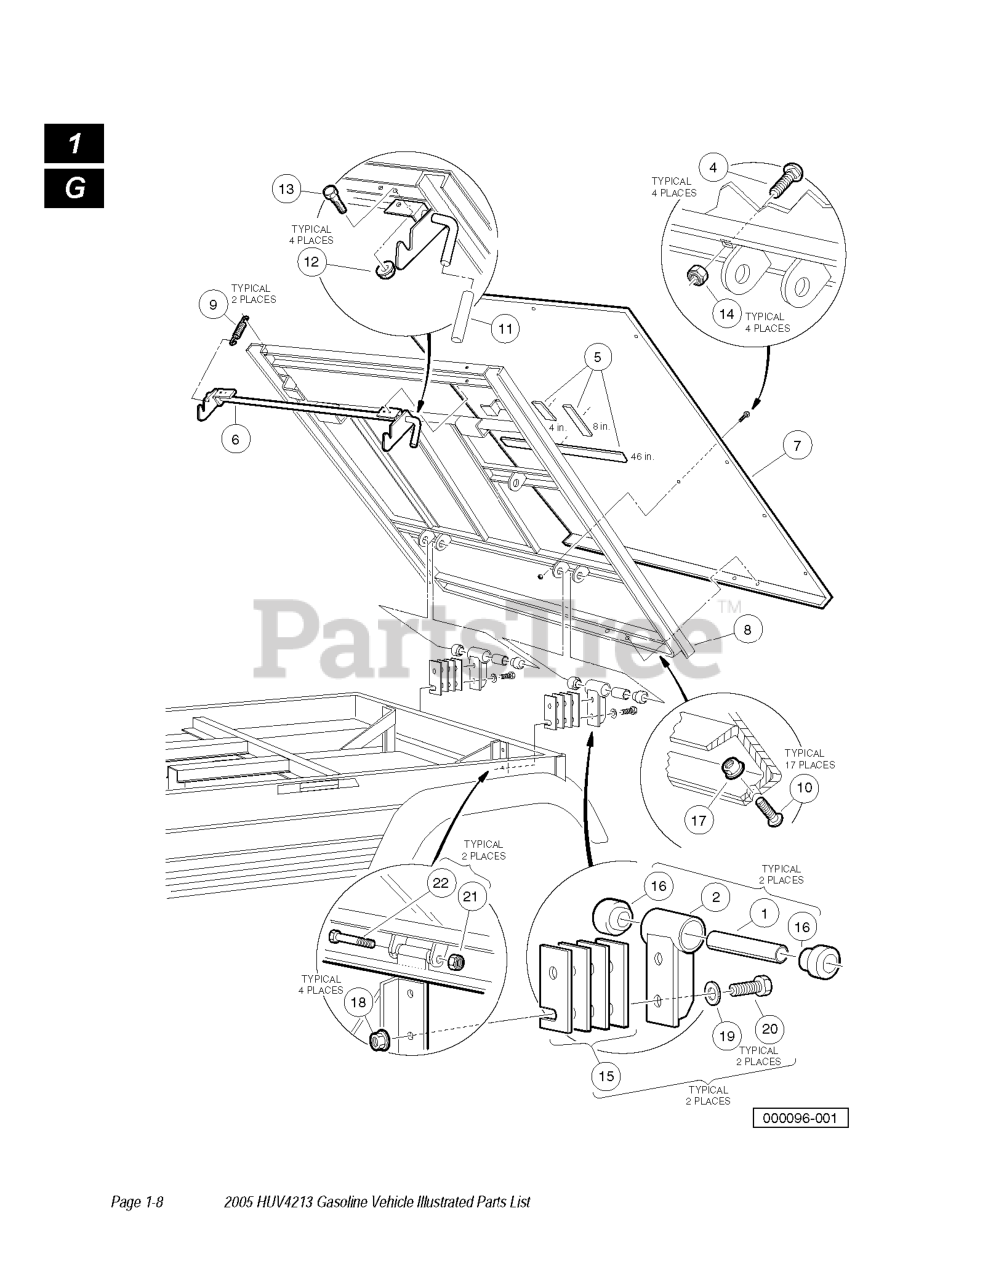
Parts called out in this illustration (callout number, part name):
1	BUSHING - STEEL (GAS CAR)
2	ASM, HINGE-TILT BED
3	TILT BED ASM CA II MANUAL LIFT
4	BOLT, 5/16-18 X 1.00 SQ.NECK
5	BOX INS.BULK
6	LATCH WELD ASSY CARRYALL
9	EXENSION SPRING LATCH CA
10	SCREW, 5/16-18 X .88 TRX TRUSS
11	GRIP, TILT LATCH HAND
12	LOCKNUT, 1/4-20 HEX WHIZ
14	LOCKNUT, 5/16-18 NYLON INSERT
15	SHIM TILT BED PIVOT
16	BUSHING, URETHANE
17	LOCKNUT, 5/16-18 HEX FLANGE
18	LOCKNUT, 3/8-16 FLANGED DIMPLE
19	WASHER, 3/8 TYPE B HARD FLAT
21	LOCKNUT, 3/8-16 HEX
22	SCREW, 3/8-16 X 3.375
